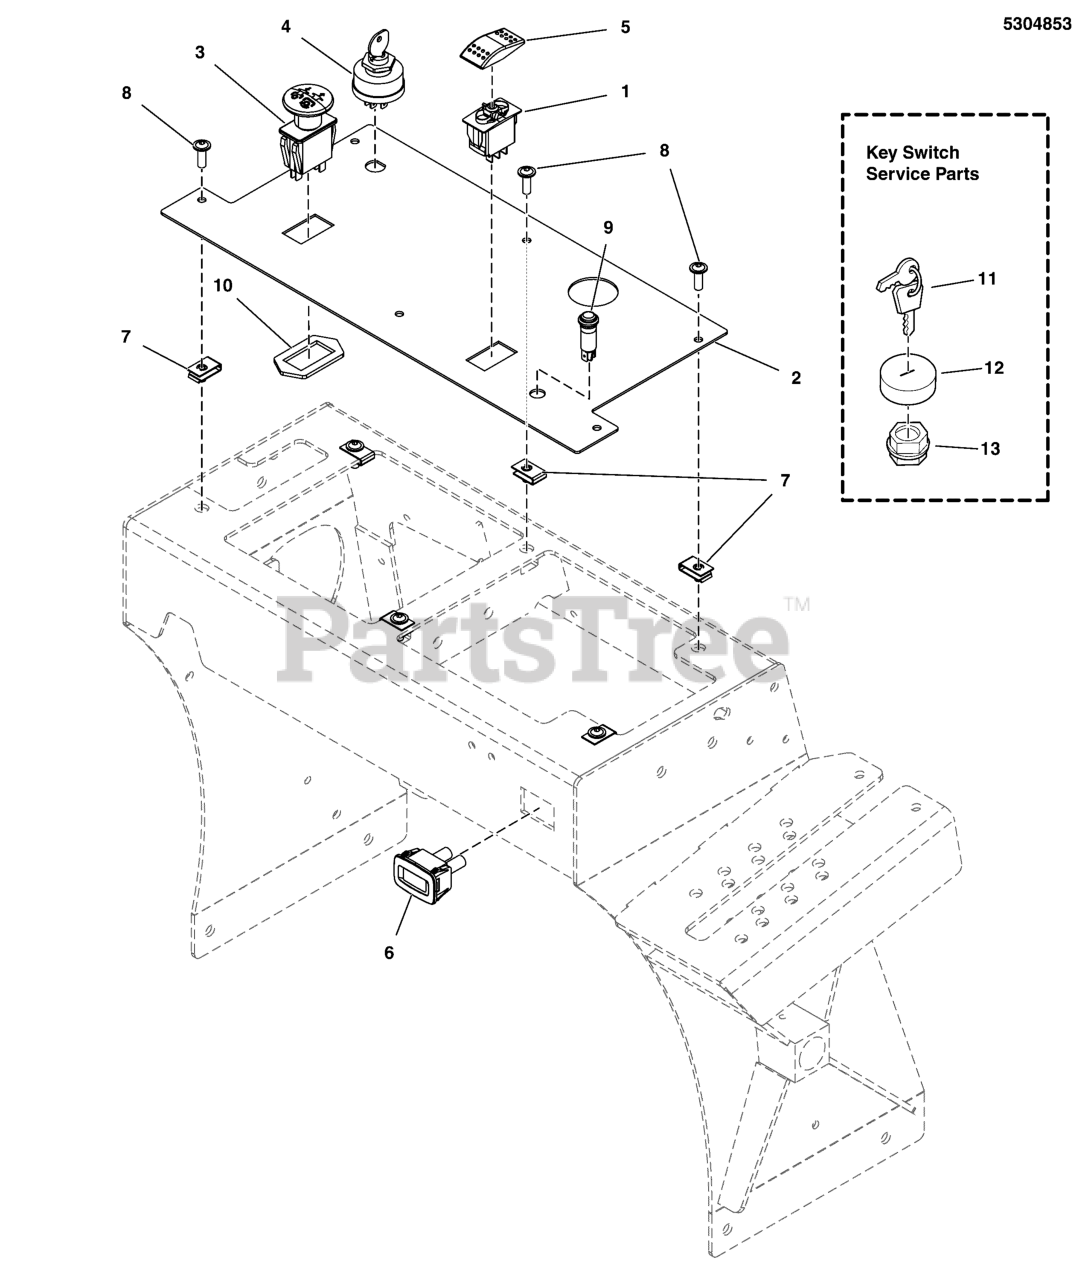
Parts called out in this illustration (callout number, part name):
1	BODY, ROCKER SWITCH
2	DASH PANEL W/DECALS, SRS Z2, KAWI EFI
3	PTO SWITCH, MOMENTARY, SMALL KNOB
4	SWITCH, IGNITION, 6 POST
5	ACTUATOR, ROCKER SWITCH - RED
6	HOUR METER
7	BODY CLIP, 1/4-20 X 1/2" DEEP
9	LIGHT, INDICATOR, PANEL, LED, RED
10	RING, SWITCH RETAINER
11	KEY, IGNITION MOLDED SET
12	COVER, PLASTIC, SNAP ON
13	PLASTIC NUT
